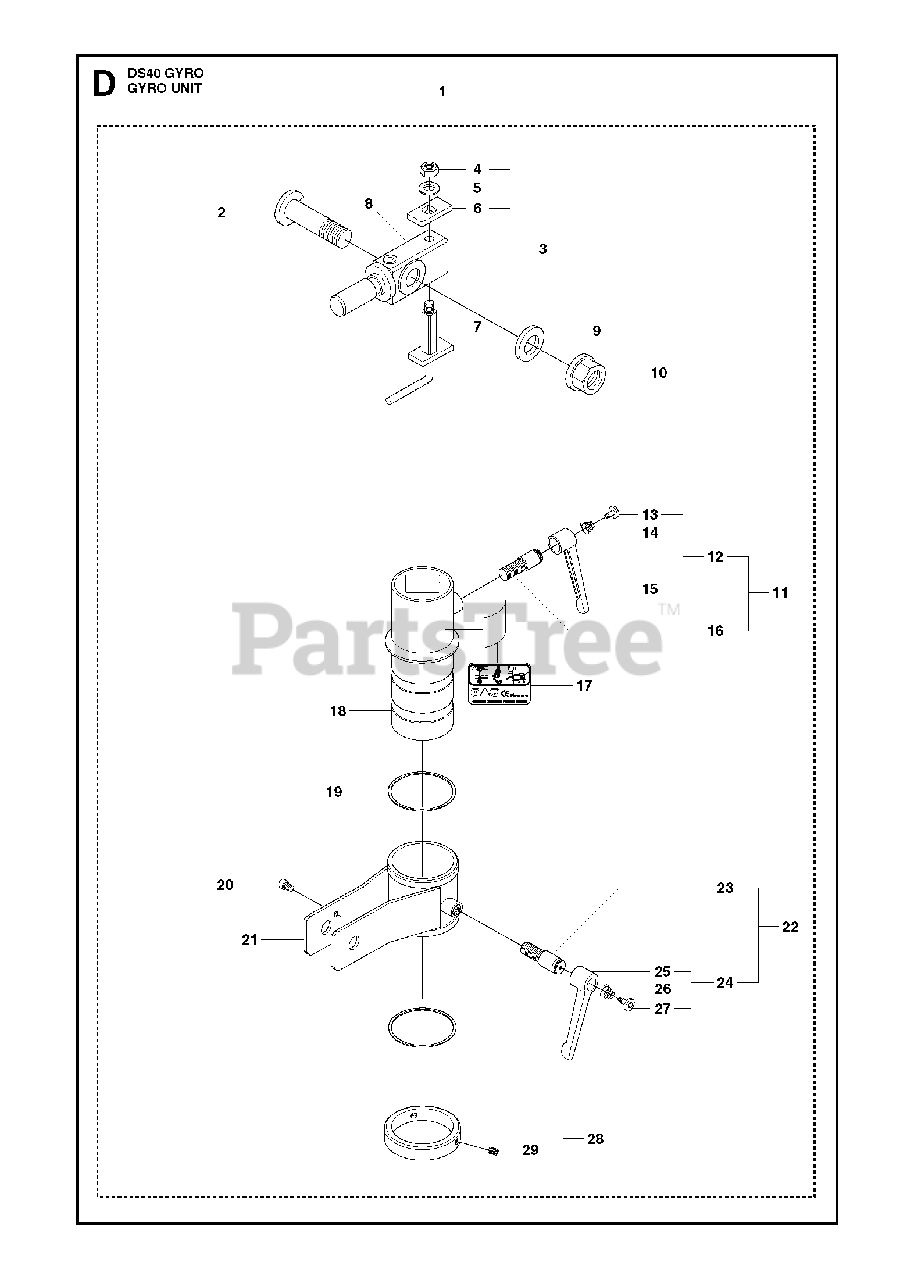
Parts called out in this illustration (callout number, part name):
1	BRACKET GYROIncl. 2, 3, 8-11, 17-22, 28
12	HANDLEIncl. 13-15
24	HANDLEIncl. 25-27
